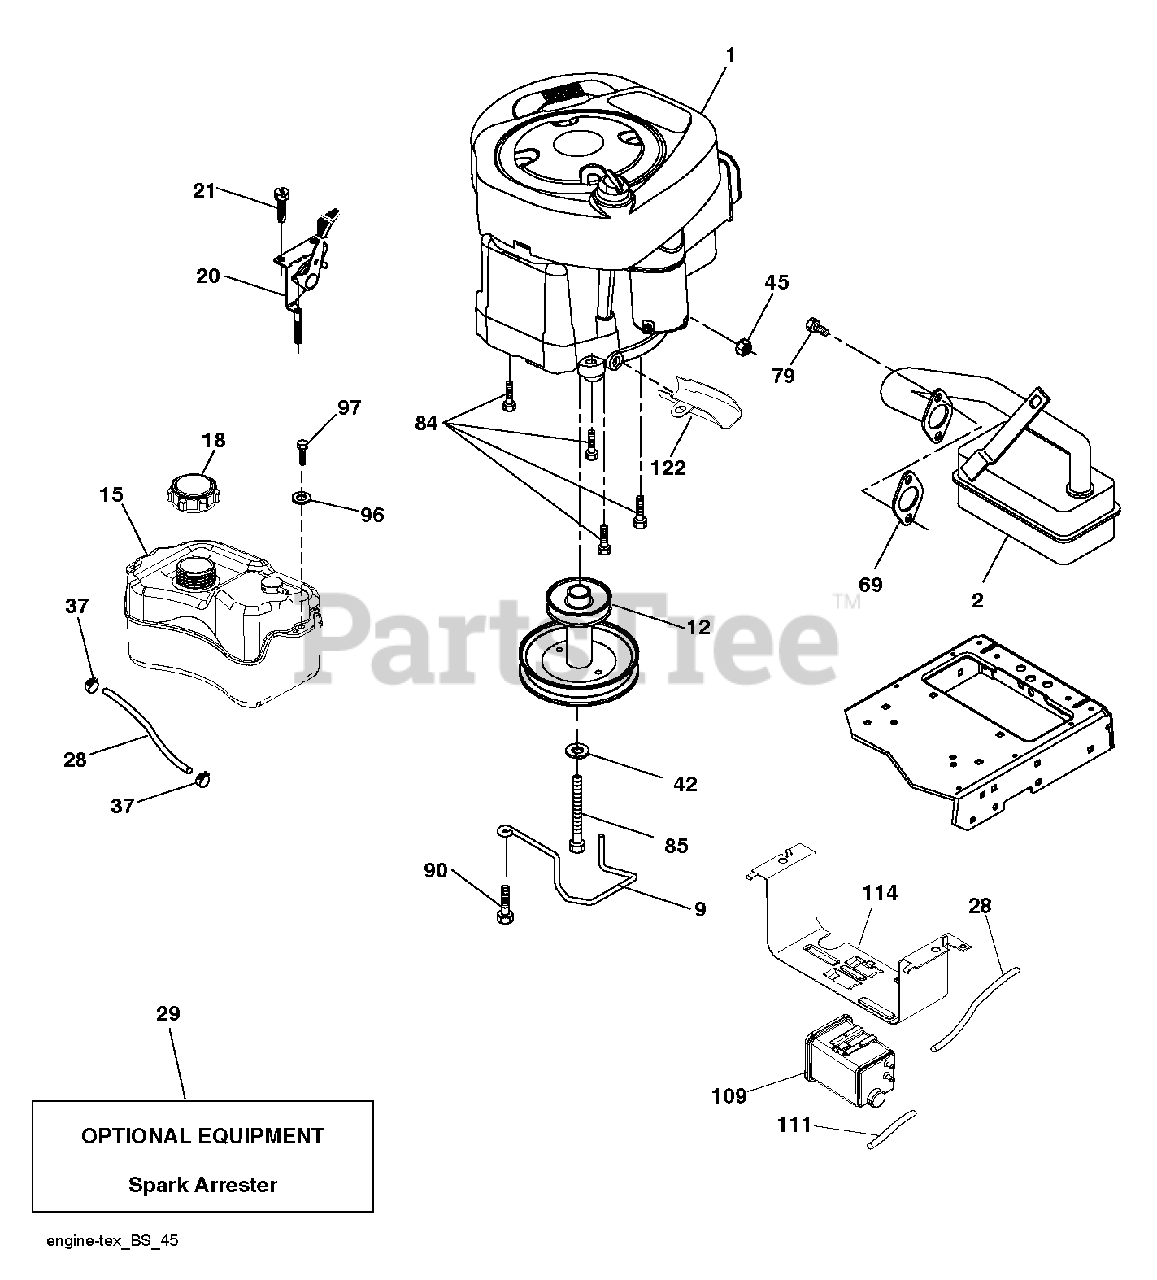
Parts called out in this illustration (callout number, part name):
2	MUFFLER.LT.BRIGGS.14HP.IC/OHV
9	KEEPER.BELT.ENGINE.4.2
12	PULLY ENGINE
15	TANK ASM.FRONT.CARB
18	CAP ASM.FUEL.2.25"FRT.CARB
21	SCREW.#10 X 0.750.BOS (2 2)
28	LINE.FUEL.20"FRONT.EMI
29	SPARK ARRESTOR KIT
37	HOSE CLAMP
42	LOCKWASHER
45	NUT
79	SCREW.SOCKET HD.5/16-1
84	SCREW.3/8-16
85	BOLT HEX 7/16-20X4-1/4"
90	SCREW 3/8-16X1
97	SCREW HEXWSHR 1/4-20X3/4
109	CANNISTER, CARBON
111	RP PURGE LINE
122	EXTENSION DRAIN OIL
